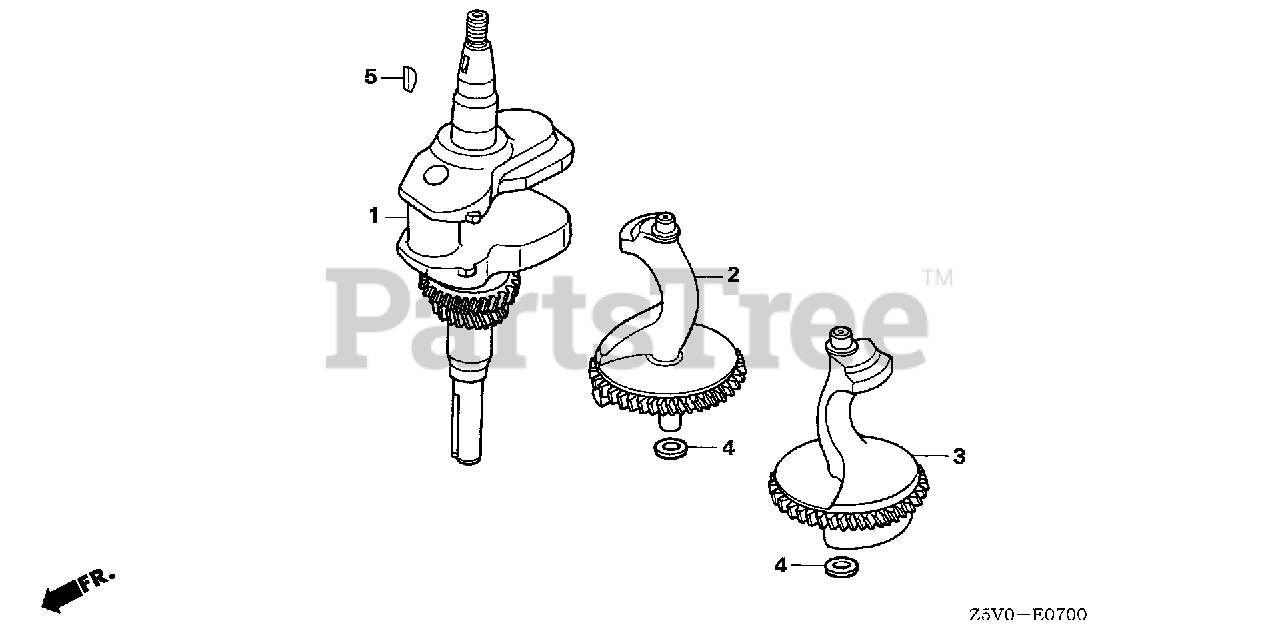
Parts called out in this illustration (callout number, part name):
1	CRANKSHAFT
2	WEIGHT A, BALANCER
3	WEIGHT B, BALANCER
4	WASHER, THRUST (14MM)
5	KEY, SPECIAL WOODRUFF (25X18)
